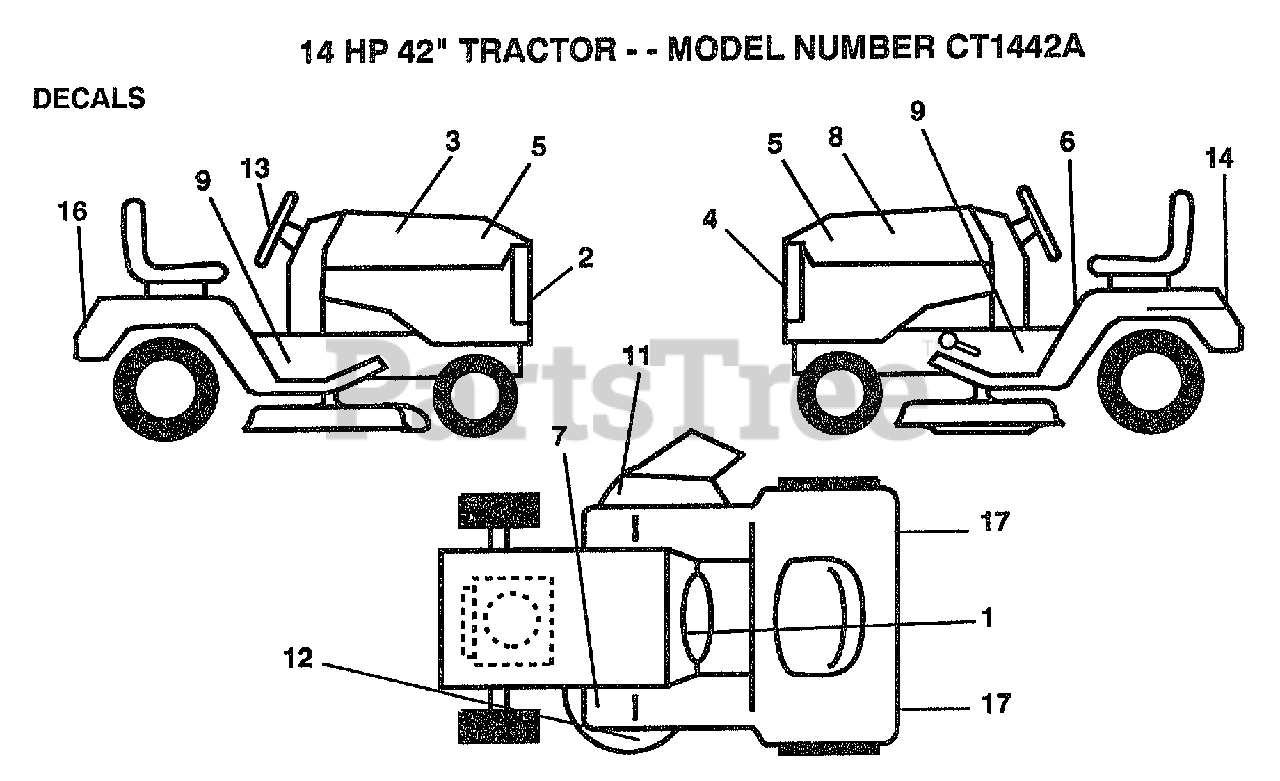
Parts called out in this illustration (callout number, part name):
2	DECAL.GRILLE
3	DECAL.HOOD.RH
5	DECAL.HOOD.INSERT
6	DECAL CAUTION
7	DECAL T
8	DECAL.HOOD.LH
9	CHASSIS DECAL
11	"DECAL, WARNING"
13	DECAL.STG.WHL.INS
14	DECAL
16	DECAL.FENDER
17	REFLECTOR-TAIL YT
